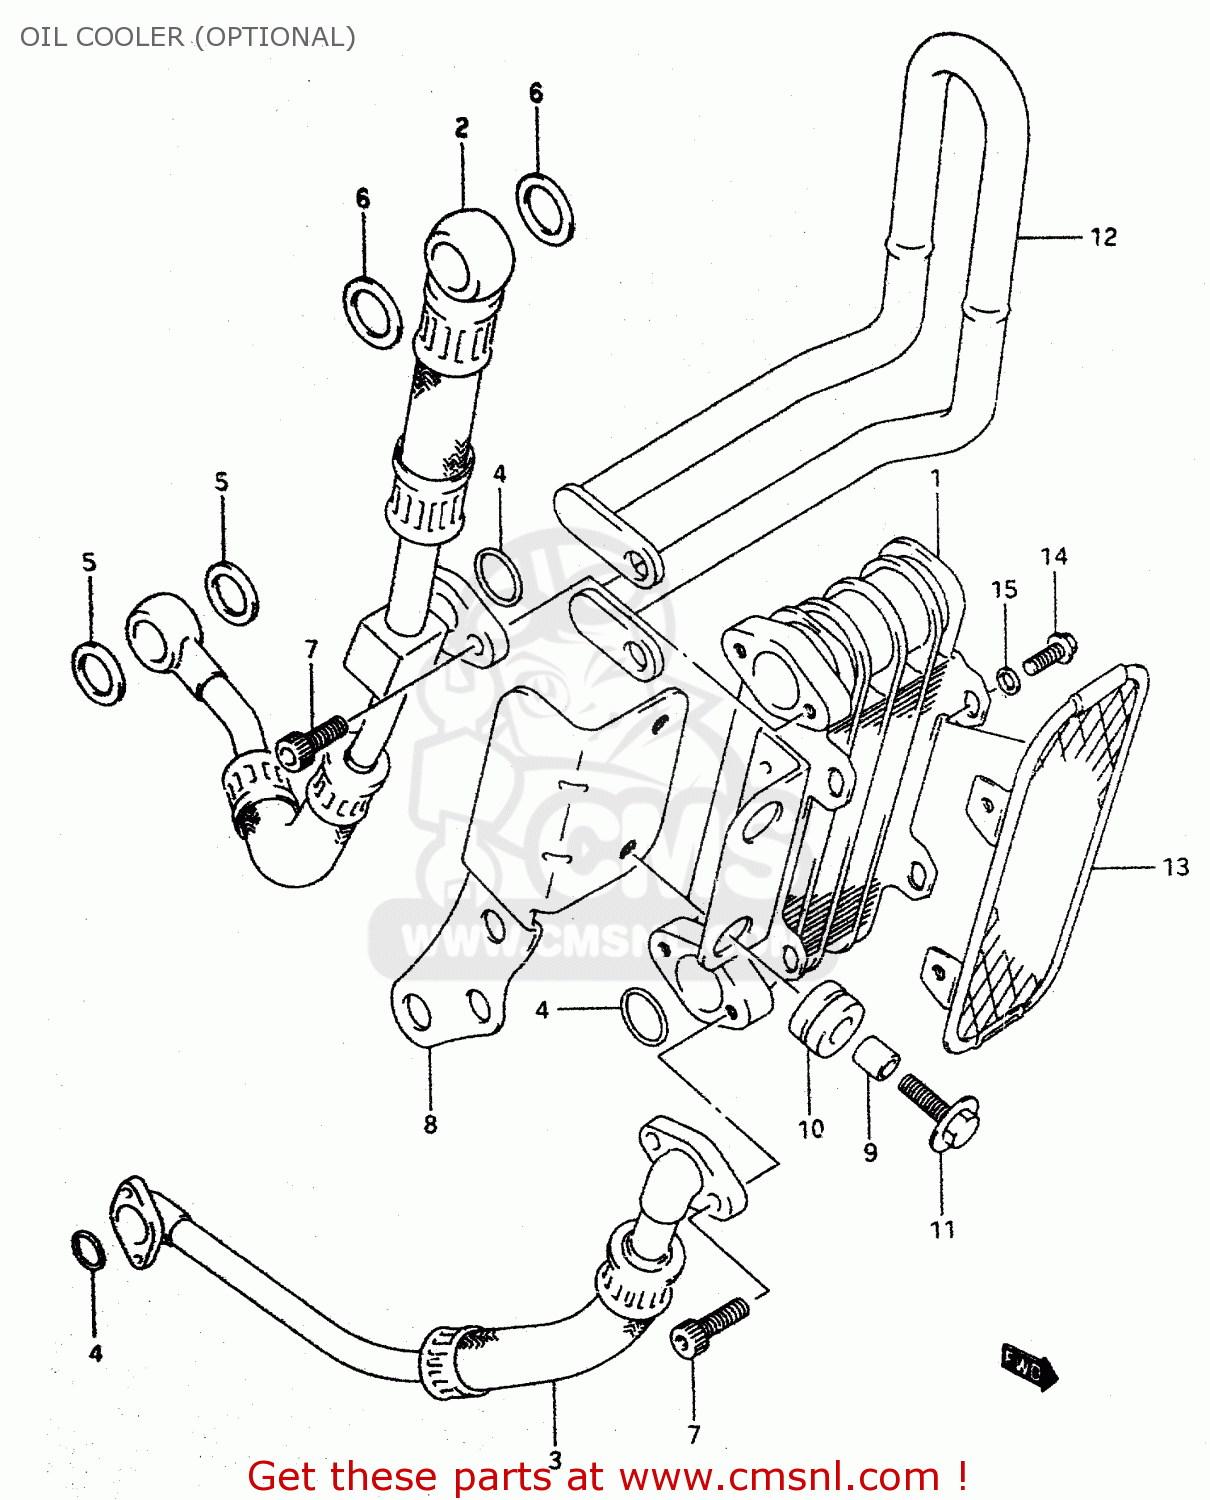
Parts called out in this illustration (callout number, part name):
1	COOLER ASSY,OIL
2	HOSE,OIL COOLER UPR
3	HOSE,OIL COOLER LWR
4	O RING(D:2.4,ID:12.3)
5	GASKET(12X17X1) (NAS)
6	GASKET(16X22X2) (NAS)
7	BOLT,OIL FILLE
8	BRACKET,OIL COOLER
9	SPACER(6.5X10X10)
10	CUSHION
11	BOLT 6X20
12	GUARD,OIL COOLER
13	BUMPER,OIL COOLER
14	BOLT
15	LOCK,WASHER
